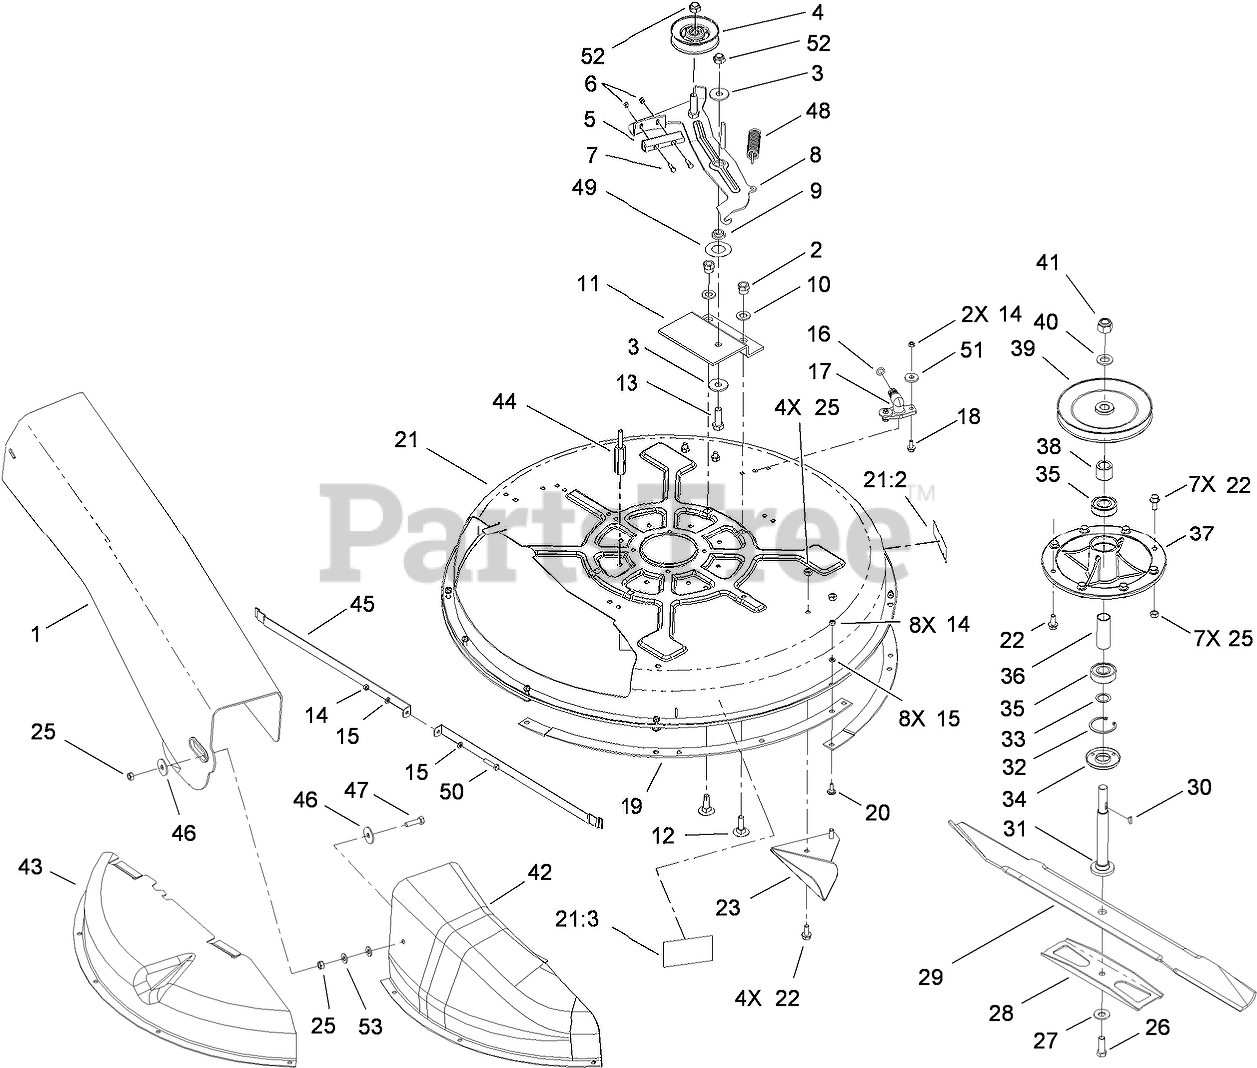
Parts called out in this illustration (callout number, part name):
1	Tube-Discharge
2	NUT-LOCK
3	Washer-Flat
4	PULLEY-IDLER
5	Brake-Rubber
6	NUT-LOCK
7	SCREW-HH
8	BRAKE ASM
9	Bushing
10	WASHER-FLAT
11	Bracket-Deck
12	SCREW-CARR
13	SCREW-HH
14	NUT-LOCK
15	WASHER-FLAT
16	O-Ring
17	FITTING-WASHOUT
18	SCREW-HHF
19	RING-DECK
20	Screw-Sh
21	DECK ASM
21:2	Decal-Caution
21:3	DECAL-COVER, DISCHARGE
22	SCREW-HHF
23	Kicker
25	NUT-LOCK
26	SCREW-HH
27	Washer-Bell
28	STIFFENER
29	Blade-Recycler
31	SHAFT-SPINDLE
32	Ring-Snap
33	Spacer
34	SHIELD-BEARING
35	BEARING-BALL
36	Spacer
37	SPINDLE
38	Spacer
39	PULLEY
40	WASHER-FLAT
41	Nut-Hex
42	Tunnel-Discharge
43	Cover-Recycler
44	Guide-Belt
45	STRAP-DECK
46	Washer-Flat
47	SCREW-HH
48	Spring-Extension
49	Spacer
50	SCREW-HH
51	Washer-Flat
52	Nut-Lock
53	WASHER-PLAIN
